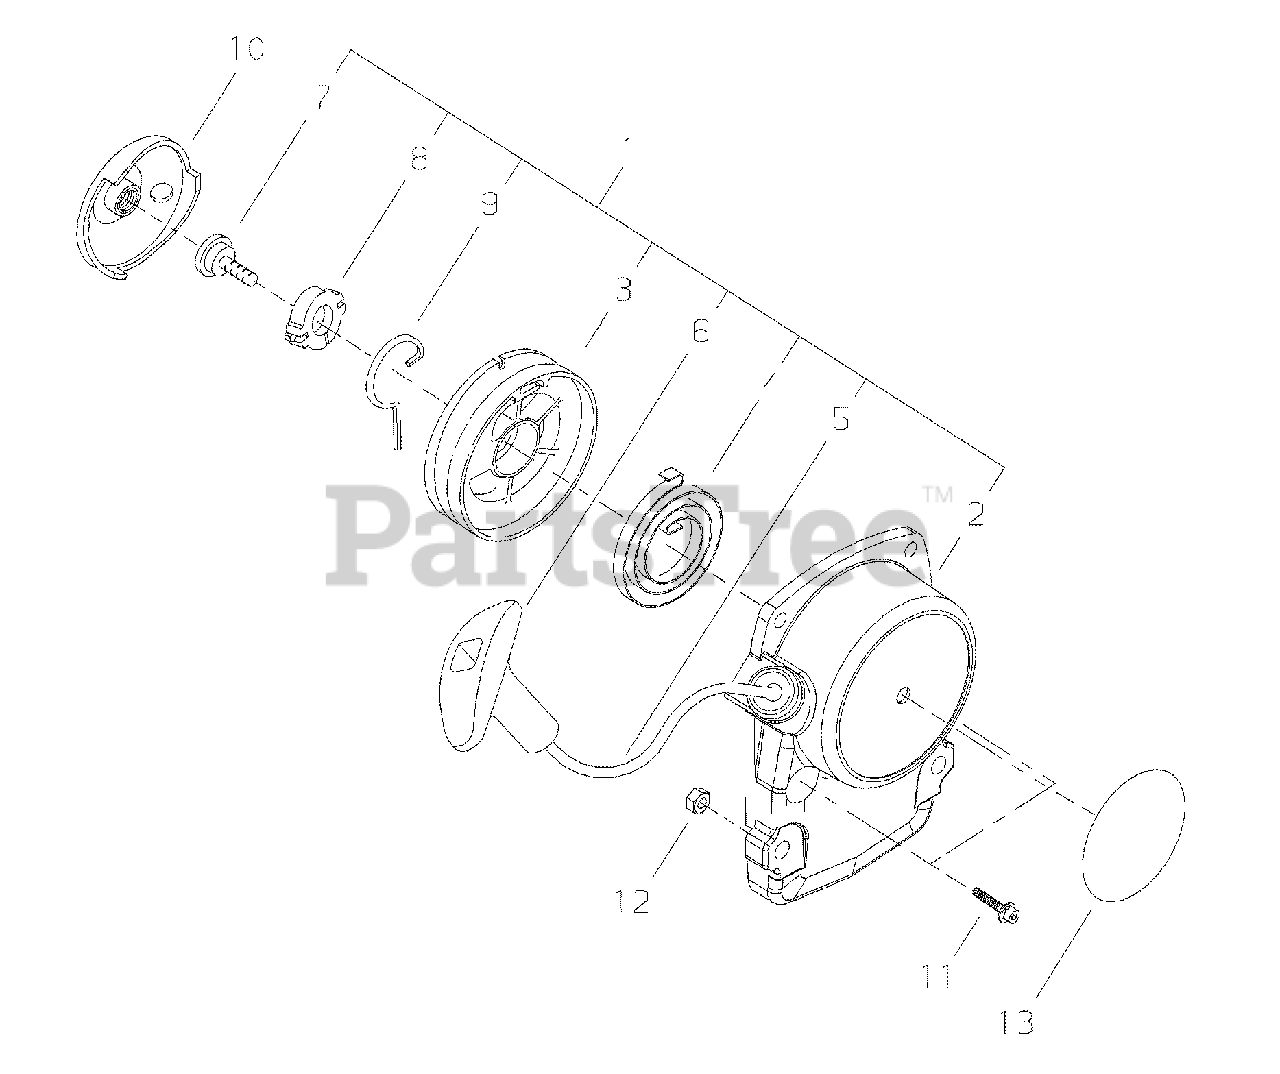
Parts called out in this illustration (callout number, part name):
1	STARTER ASSY, RECOIL
2	CASE, RECOIL STARTER
3	REEL, ROPE
4	SPRING, RECOIL
5	ROPE, STARTER
6	GRIP, STARTER
7	SCREW 5
8	WASHER 5
9	ARM, SWING
10	PULLEY, STARTER
11	BOLT M4×16
12	NUT M5
13	LABEL - SHINDAIWA
